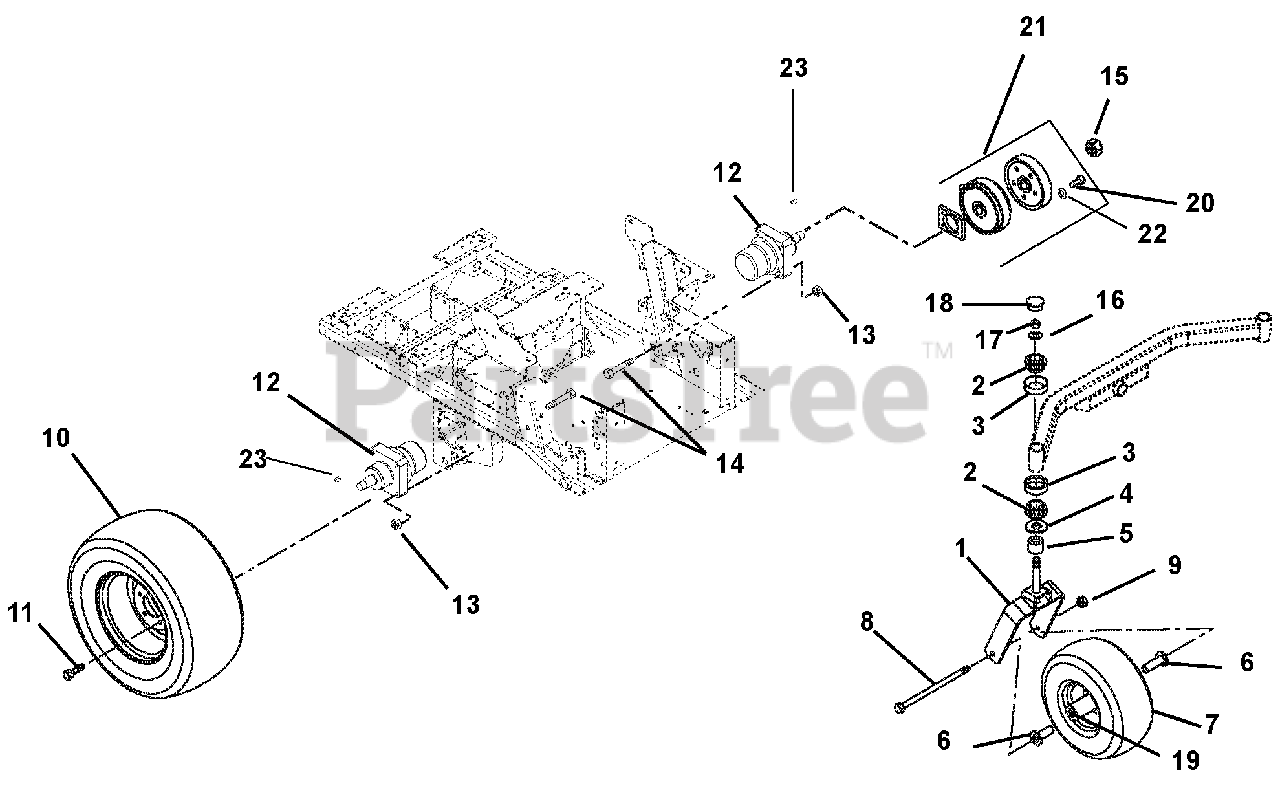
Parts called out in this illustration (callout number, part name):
1	Fork, Front
2	Bearing, Cone w/ Grease
3	Bearing, Cup 1.980 x .420
4	Bearing Seal 1.5 x 2 x .18
5	Spacer, PM, 1.03 I.D. x 1.5 O.D. x .375
6	Spacer, Wheel
7	Wheel/Tire Assembly 15 x 6-6
8	Bolt, Hex .50-13 x 9.00 Grade 5
9	Nut, Locking Center .50-13
10	Tire/Wheel Assembly 24 x 11.50-12
11	Bolt, Lug .50-20 x 1.38
12	Hydraulic Wheel Motor (Includes item 15)
13	Nut, Locking Top Flange .50-13
14	Bolt, Hex .50-13 x 2.75 Grade 8
15	Nut, Lock Jam Patch (Included with 12)
16	Washer, Flat Steel 812 x 1.50 x .135
17	Nut, Jam Center Lock .75-16
18	Cap, Dust
19	Bearing, 25mm I.D. x 52mm OD x 15mm
20	Bolt, Hex .31-18 x 1.5 Grade 8 EP30
21	Kit, Parking Brake Service
22	Washer, Lock .31 x .078
23	Key, Woodruf .31 x 1.00 (For service only)
